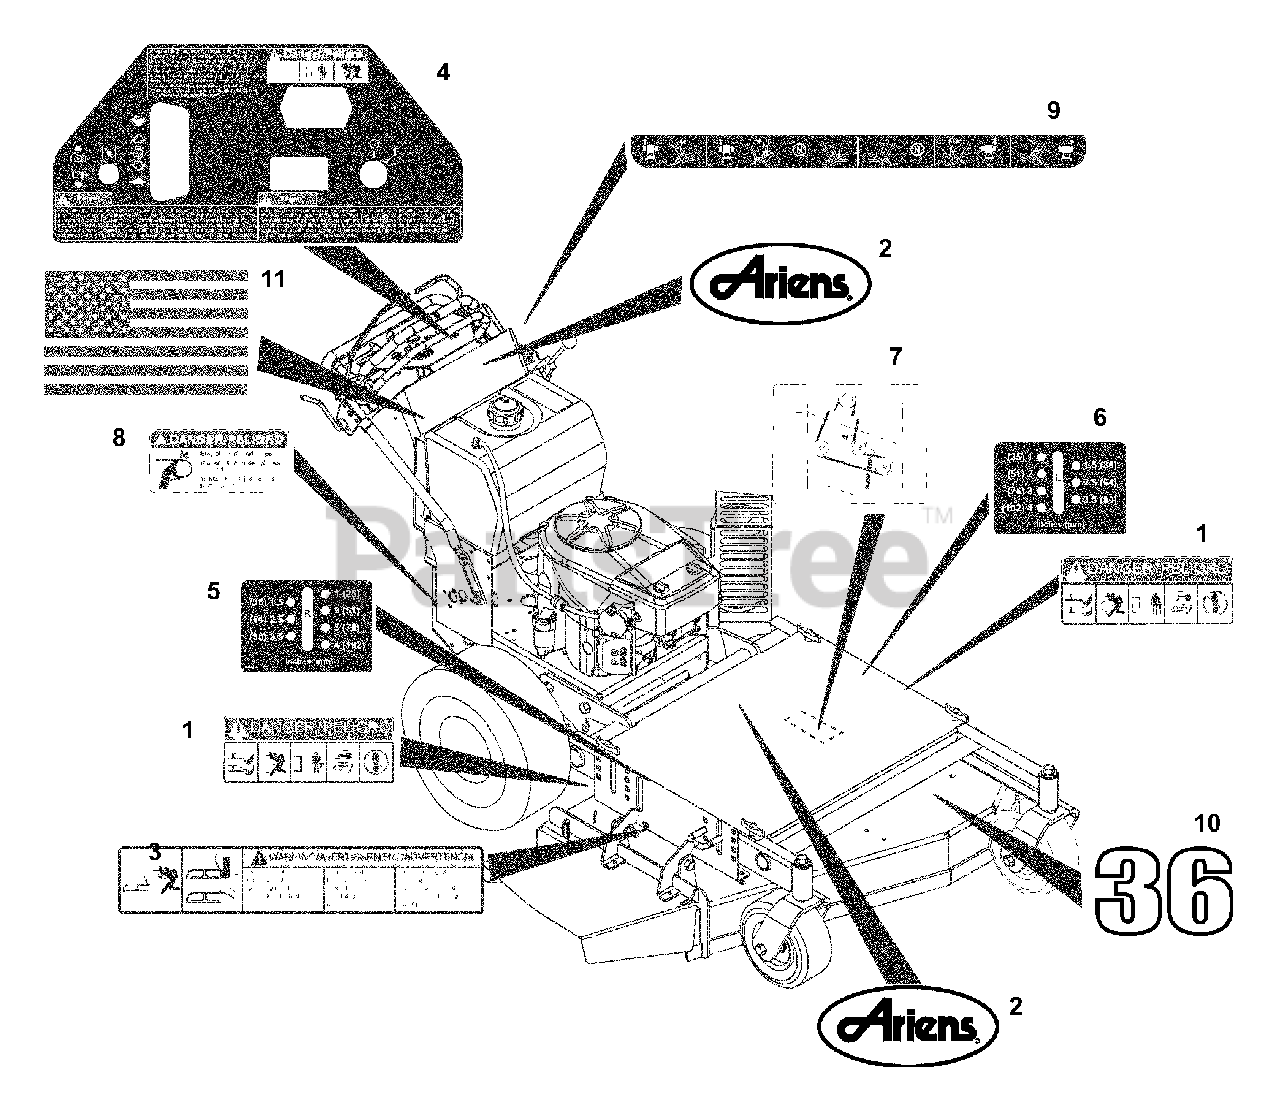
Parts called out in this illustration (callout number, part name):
1	DECAL, MOWER PAN DANGER
2	DECAL, ARIENS
3	DECAL, WARNING
4	DECAL - CONTROL HR15 - ERGO
5	DECAL-HEIGHT OF CUT-FIXED - RH
6	DECAL-HEIGHT OF CUT-FIXED - LH
7	DECAL-BELT DIAGRAM-2 SPINDLE
8	DECAL-DANGER-BELT ROTATING
9	DECAL-STEER LEVERS-HYDRO-ERGO
10	DECAL, 36
11	DECAL, AMERICAN FLAG
